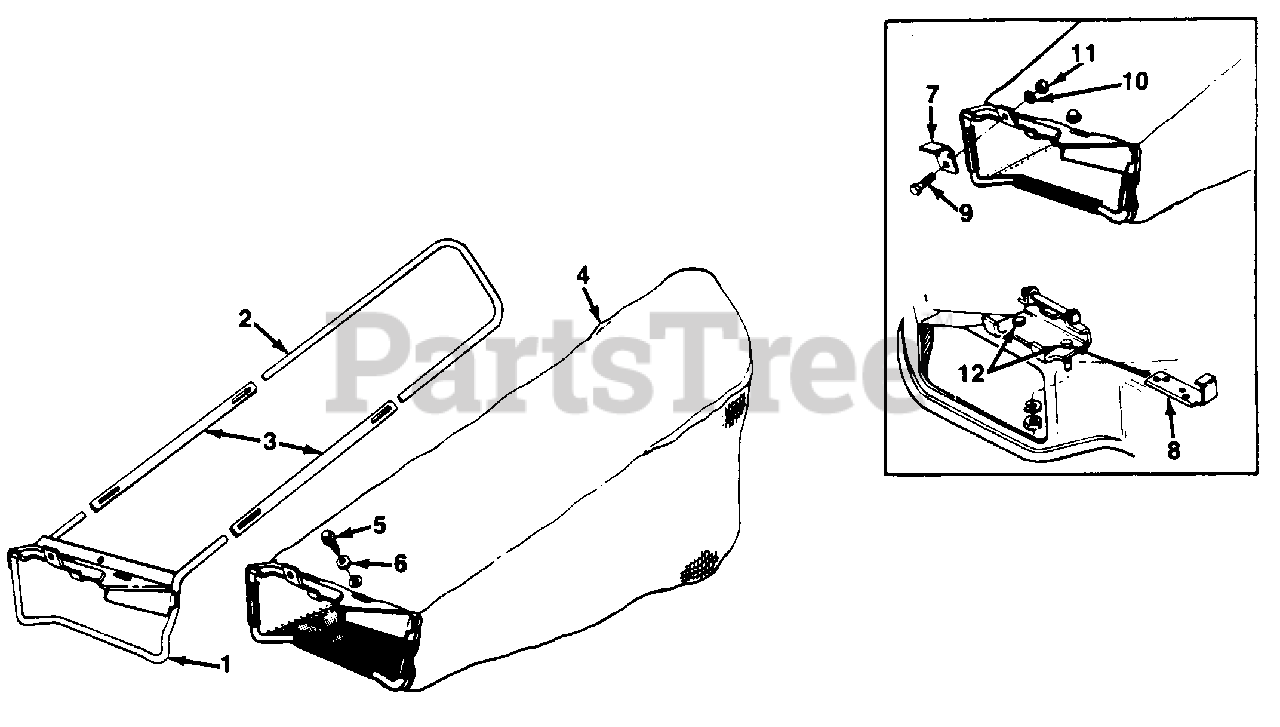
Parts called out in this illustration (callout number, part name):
4	Grass Bag
5	Hex Wash Hd. TT-Tap Scr. 1/4-20 x 5" Lg.
6	Bell-Wash. 1/41. D.
7	Deflector Stop
8	Support Plate
9	Hex Bolt 1/4-20 x 5" Lg .
10	L-Wash. 1/4" 1. D.
11	Hex Nut 1/4-20 Thd.
12	Hex Bolt 1/4-20 x .62" Lg.
